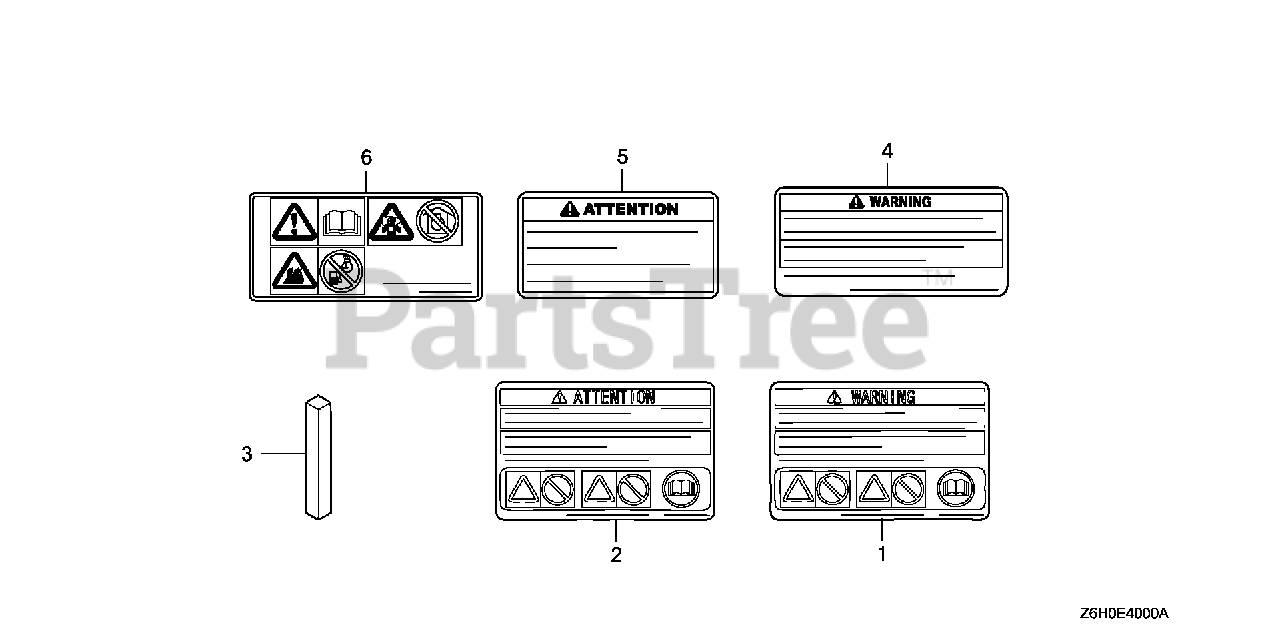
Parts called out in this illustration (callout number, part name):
2	MARK, OPERATOR CAUTION (FRENCH)(MADE IN JAPAN)
3	KEY (6.3X6.3X43)
5	MARK, OPERATOR CAUTION (FRENCH)(MADE IN JAPAN)
6	MARK, OPERATOR CAUTION (PICTOGRAPH)
